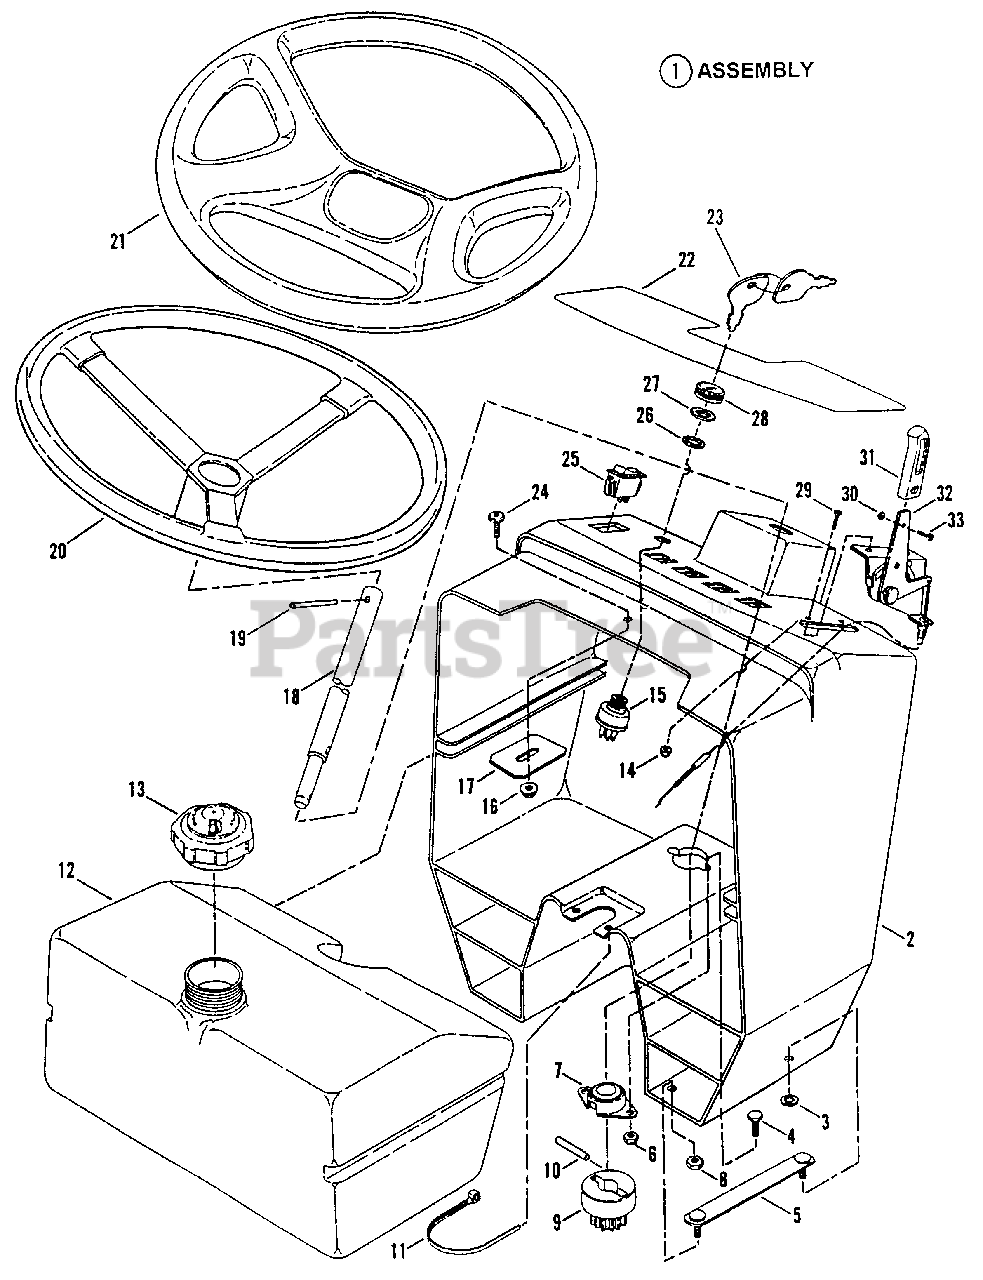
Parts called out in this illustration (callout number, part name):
1	ASSEMBLY, Console
2	CONSOLE
3	RETAINER
4	SCREW, 1/4-20 x 3/4" Hex Head Cap, Grade 5
5	ASSEMBLY, Strap-Clinch Stud
6	NUT, 1/4-20 Hex Nyloc
7	ASSEMBLY, Flange Bearing
8	NUT, 5/16-18 Hex Center Lock, Grade 5
9	GEAR, Pinion, Steering Shaft
10	PIN, Dowel, 1/4 x 1-1/4"
11	TIE, Wire
12	ASSEMBLY, Fuel Tank
13	CAP, Fuel Tank
14	NUT, #10-24 Hex Nyloc
15	KEYSWITCH (Gear Drive Models)
15	KEYSWITCH (Hydro Drive Models)
16	NUT, 5/16-18 Hex Flange Center Lock
17	BRACKET, Hood Latch Catch
18	SHAFT, Steering
19	ROLL-PIN
20	STEERING WHEEL (Gear Drive Models)
21	STEERING WHEEL (Hydro Drive Models)
22	DECAL, Console, (Gear Drive Models - Without Lights)
22	DECAL, Console (Hydro Drive Models - With Lights)
23	KEY, Pair
24	SCREW, 5/16-18 x 5/8" Truss Head, Torx
25	SWITCH, Lights (Hydro Drive Models)
27	NUT, 5/8-32 Hex
28	BEZEL
29	SCREW, #10-24 x 5/8" Machine
30	NUT, #8-32 Hex
31	HANDLE, Throttle Control
32	CONTROL, Throttle
33	SCREW, #8-32 x 3/8" Cross-Recessed, Machine
